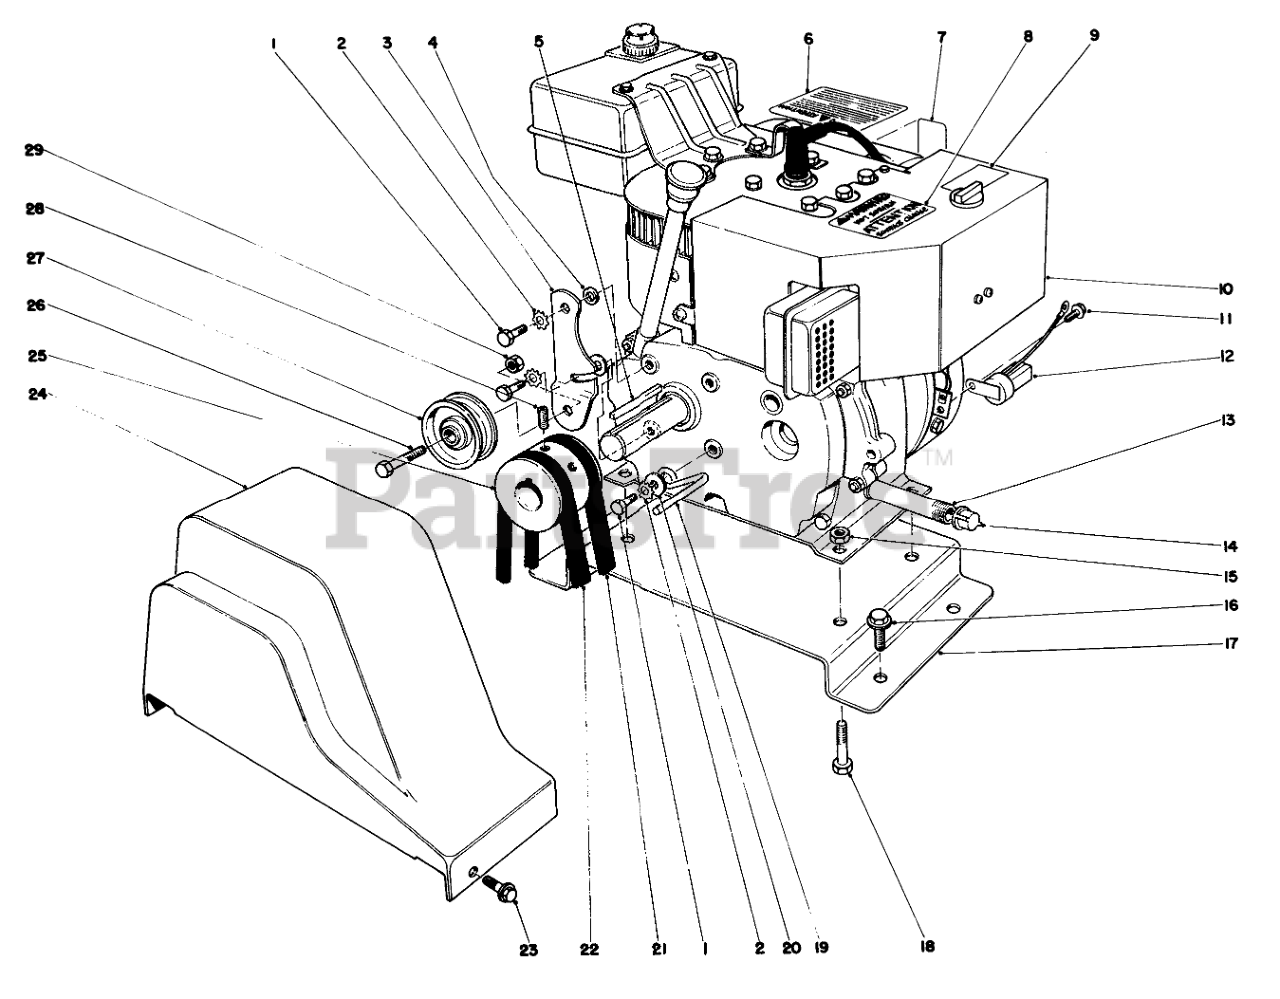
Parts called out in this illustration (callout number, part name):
1	SCREW-HH
2	WASHER-LOCK
3	ENGINE IDLER ARM
4	SPACER
6	Decal-Hazard
7	PRIMER DECAL
8	Decal Hot Surface Warning
9	CHOKE DECAL
10	Engine
11	SCREW
12	INTERLOCK MODULE
13	NIPPLE-PIPE
14	CAP-PIPE
15	NUT-LOCK, NI
16	SCREW-HHFTF
17	ENG MTG PLATE R
18	SCREW-HH
19	BELT RETAINER
20	WASHER-PLAIN
21	V-BELT
22	V-BELT
23	SCREW-HWH
24	BELT GUARD
25	ENGINE PULLEY
26	SCREW-HH
27	PULLEY-IDLER
28	Screw-Set
29	NUT-HEX
